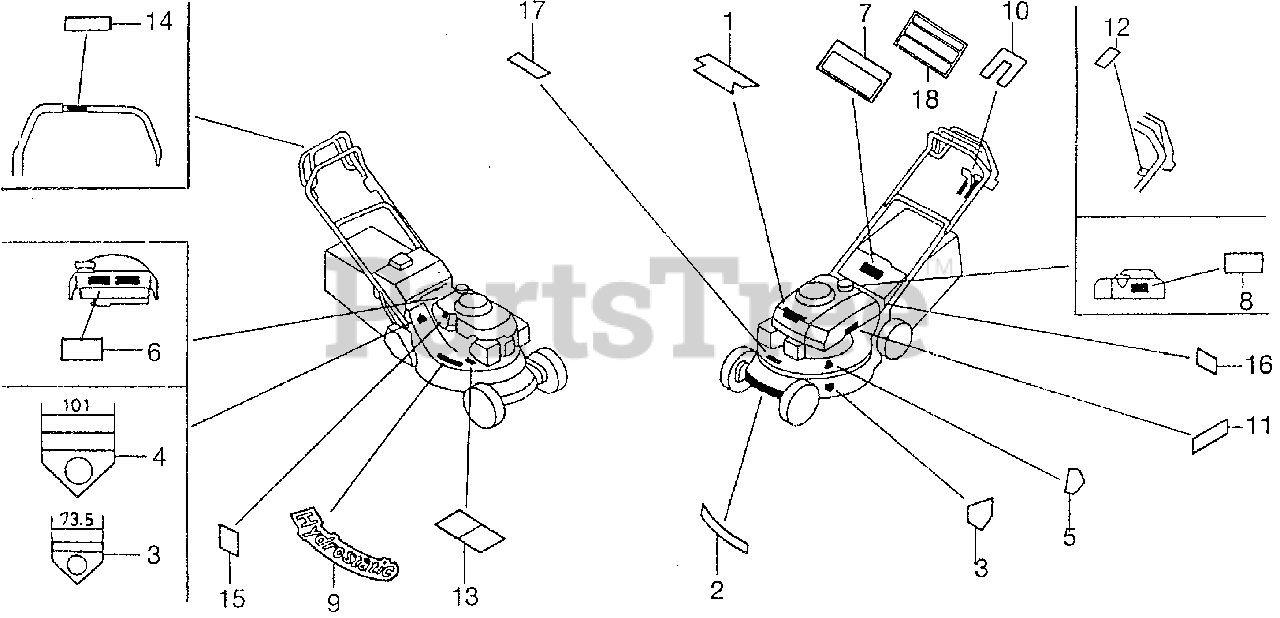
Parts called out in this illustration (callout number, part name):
1	MARK, EMBLEM
2	LABEL A, HOUSING CAUTION
3	LABEL B, HOUSING CAUTION (ENGLISH)
4	CAUTION C, HOUSING
5	LABEL, STEP POSITION (ENGLISH)
7	LABEL, WARNING (ENGLISH)
8	LABEL, FUEL WARNING (B)(ENGLISH)
11	MARK, AIR CLEANER CAUTION (ENGLISH)
12	MARK, THROTTLE (ENGLISH)
14	MARK, BLADE CONTROL (ENGLISH)
15	MARK, OIL CAUTION
16	MARK, TYPE (PXA)
17	MARK, TYPE (PX)
